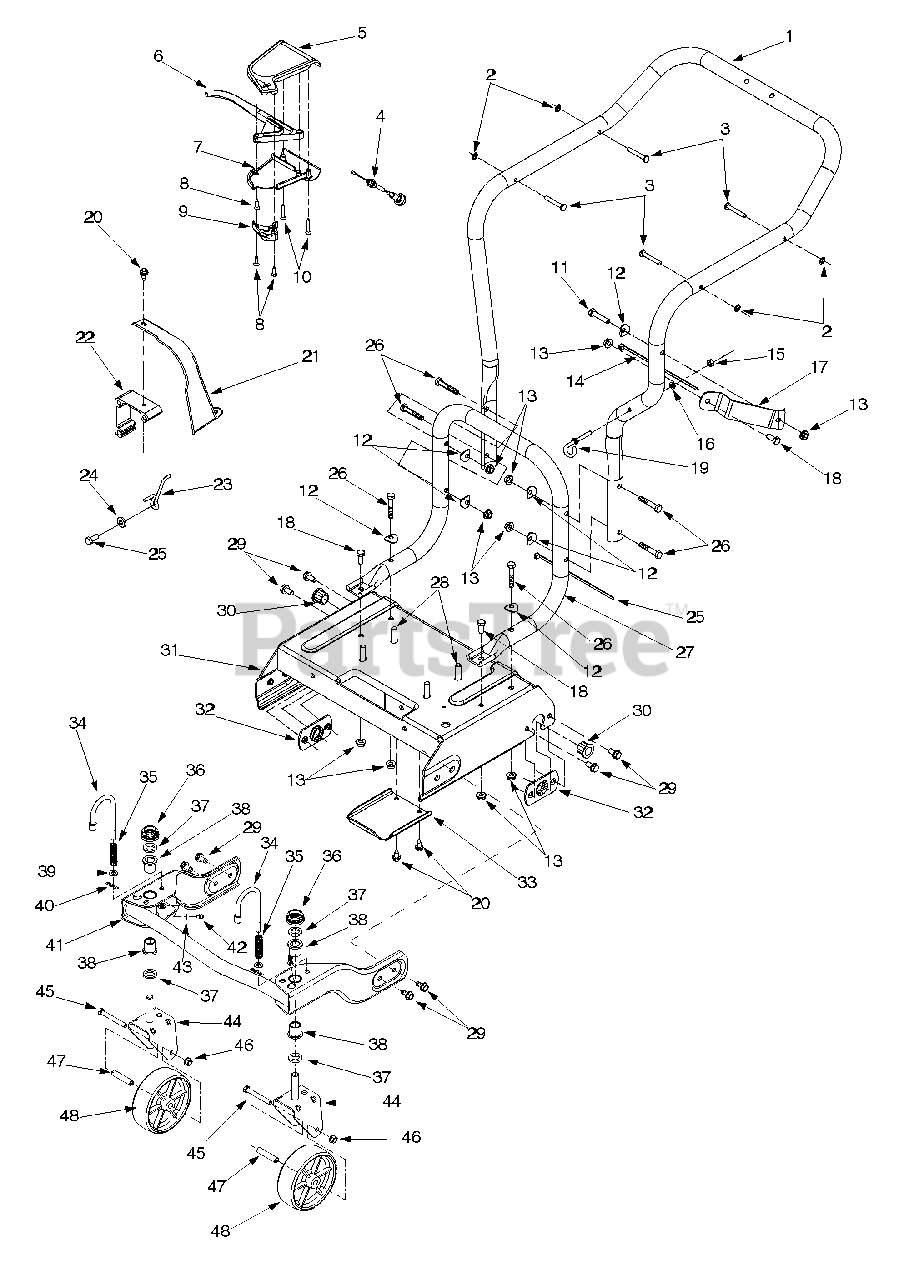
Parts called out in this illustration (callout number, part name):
3	Stud Pin .250 x 1.75
4	Clutch Cable 56"
5	Upper Clutch Cover
6	Drive Lever
7	Lower Clutch Cover
8	Screw #10-12 x .750
9	Mounting Cable Cap
10	Screw #10-16 x 1.25
11	Hex Cap Screw 5/16-18 x 1.50
12	Shoulder Washer .320 ID x .93 OD
13	Hex Flange Lock Nut 5/16-18
14	Cable Tie
15	Hex Nut 1/4-28
16	Lock Washer 1/4
18	Hex Cap Screw 5/16-18 x .75
20	Hex Washer Screw 1/4-14 x .625
21	Belt Cover
22	Engine Mounting Adapter
23	Belt Keeper
24	Flat Washer .344 x .75 x .12
25	Hex Cap Screw 5/16-24 x .75
26	Hex Cap Screw 5/16-18 x 1.75
29	Hex Washer Screw 5/16-18 x .625
30	Hex Flange Bearing .631 x .720
35	Compression Spring
37	Flat Washer 5/8 ID x 1.0 OD
38	Flange Bearing .632 ID
39	Flat Washer .330 ID x .630 OD
40	Cotter Pin
42	Grease Fitting 3/16
43	Flat Washer .203 ID x .403 OD
45	Hex Cap Screw 3/8-16 x 3.0
46	Flange Lock Nut 3/8-16
48	Wheel 6.0 x 2.0
